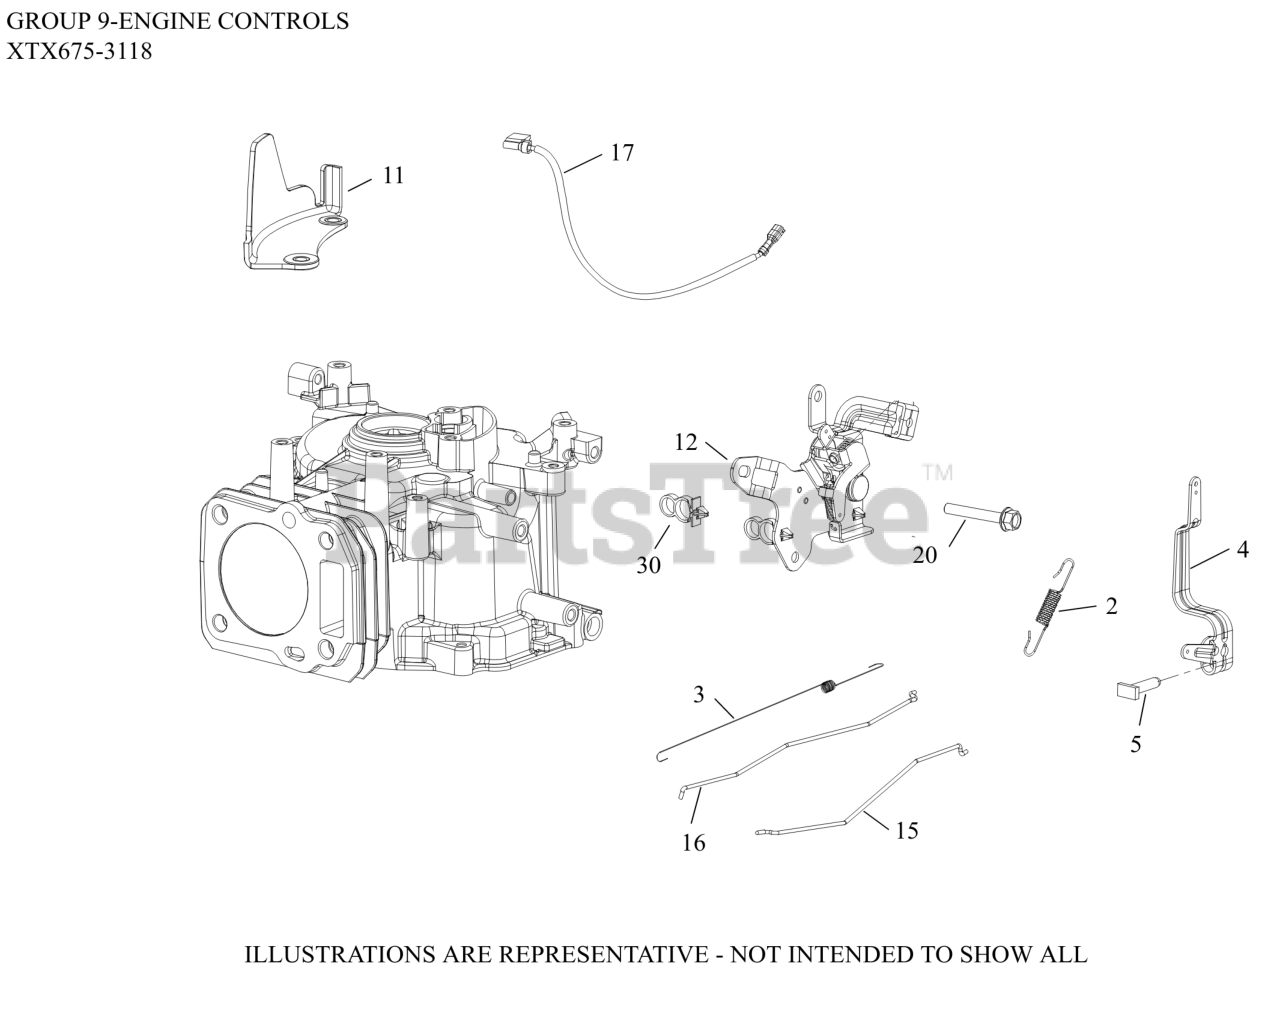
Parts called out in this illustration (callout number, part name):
2	SPRING, GOV (2800-3300 RPM)
3	SPRING, LINKAGE
5	SCREW, RECTANGLE HEAD (M6)
11	GUARD, FINGER
12	CONTROL ASSY, REMOTE VARIABLE SPEED
15	LINKAGE, CHOKE
16	LINKAGE, GOVERNOR
18	GUARD, FINGER
20	SCREW, HEX FLANGE (M6)
30	CLIP, FUEL LINE
34	LEVER, GOVERNOR
